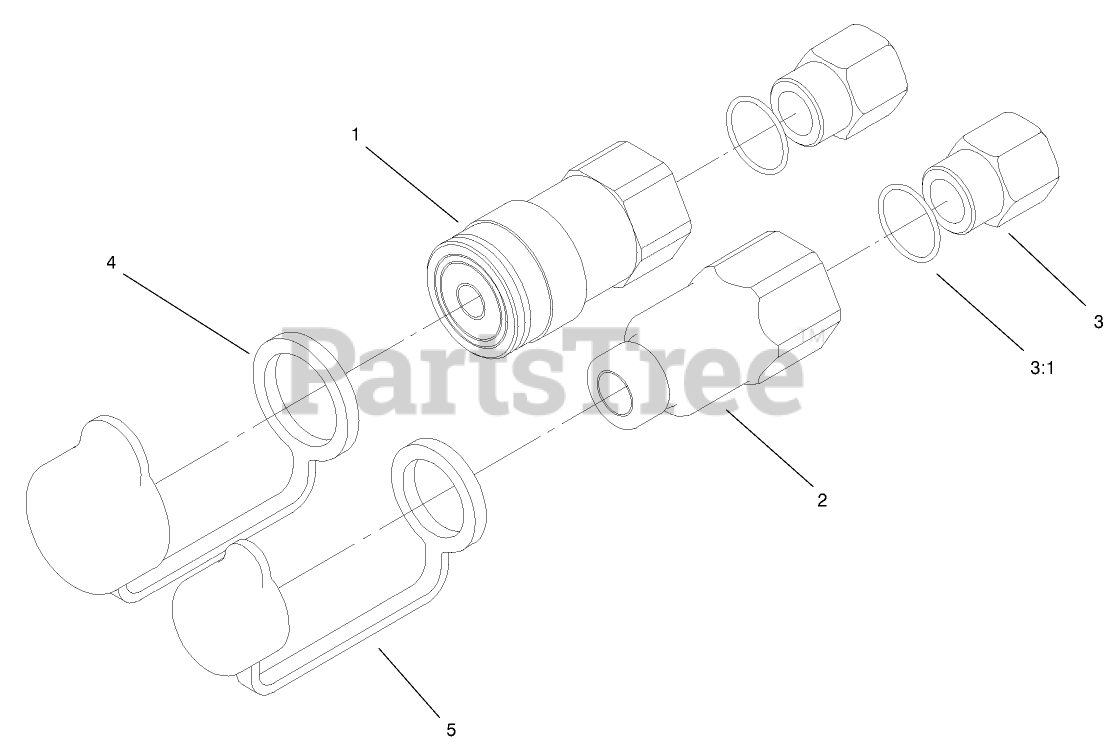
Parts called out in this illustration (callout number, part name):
1	COUPLER-FACE, FLUSH
2	NIPPLE-FACE, FLUSH
3	ADAPTER-HYD
3:1	O-RING
4	CAP-DUST, COUPLER
5	CAP-DUST, NIPPLE
